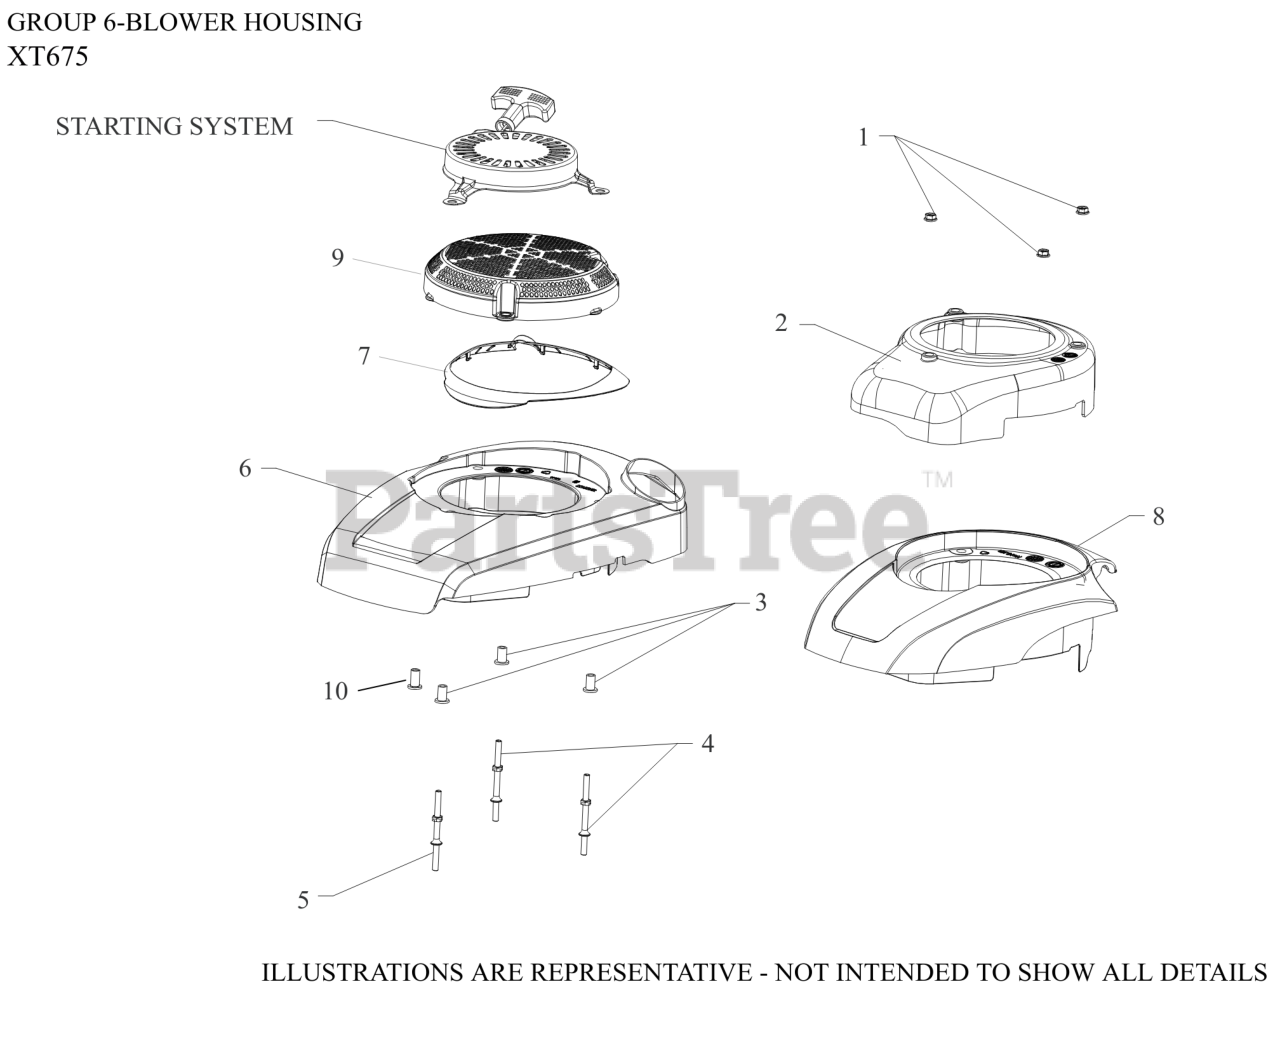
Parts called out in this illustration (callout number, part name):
1	NUT, HEX FLANGE (M6)
2	HOUSING, BLOWER
4	STUD, BLOWER HOUSING (IGNITION)
5	STUD, BLOWER HOUSING (IGNITION)
NI	NUT, LOCK M6
